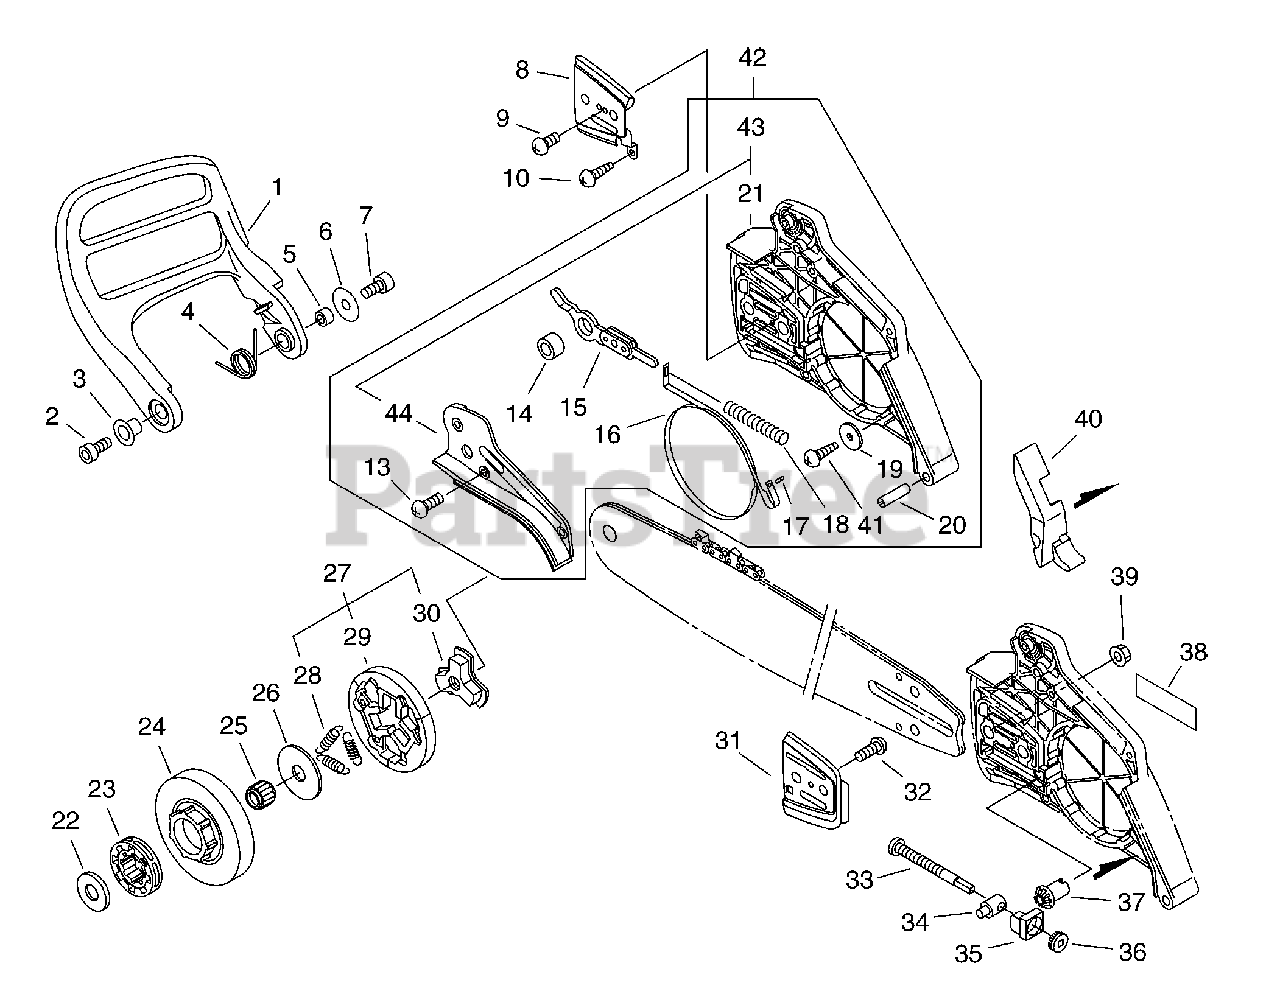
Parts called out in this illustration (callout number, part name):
1	LEVER, BRAKE
2	SCREW - 5X30
3	COLLAR - 10
5	SPACER - 8
7	SCREW - 4X14
8	PLATE, GUIDE - OUTER
9	SCREW - 3X6
10	SCREW - 4X12 -- TAPPING
12	COVER, BRAKE
13	SCREW - 4X12 -- TAPPING
14	SPACER - 8
15	CONNECTOR, BRAKE
16	BAND, BRAKE
17	PIN - 3X12
20	PIN - SPRING
21	GUARD, SPROCKET
22	PLATE, CLUTCH
23	SPROCKET, RIM
24	DRUM, CLUTCH
25	BEARING, NEEDLE
26	PLATE, CLUTCH
27	CLUTCH ASSY
28	SPRING, CLUTCH
29	CLUTCH SHOE SET
30	HUB, CLUTCH
31	PLATE, GUIDE - INNER
32	SCREW - 4X6
33	SCREW, TENSIONER
34	TENSIONER, CHAIN
35	COLLAR - 8
36	GEAR - BEVEL
37	GEAR - PINION
38	LABEL - ECHO
39	NUT - 8 -- FLANGE
40	CUSHION
41	SCREW - 4X16
42	CHAIN BRAKE ASSY
43	SPROCKET GUARD KIT
44	COVER, BRAKE
